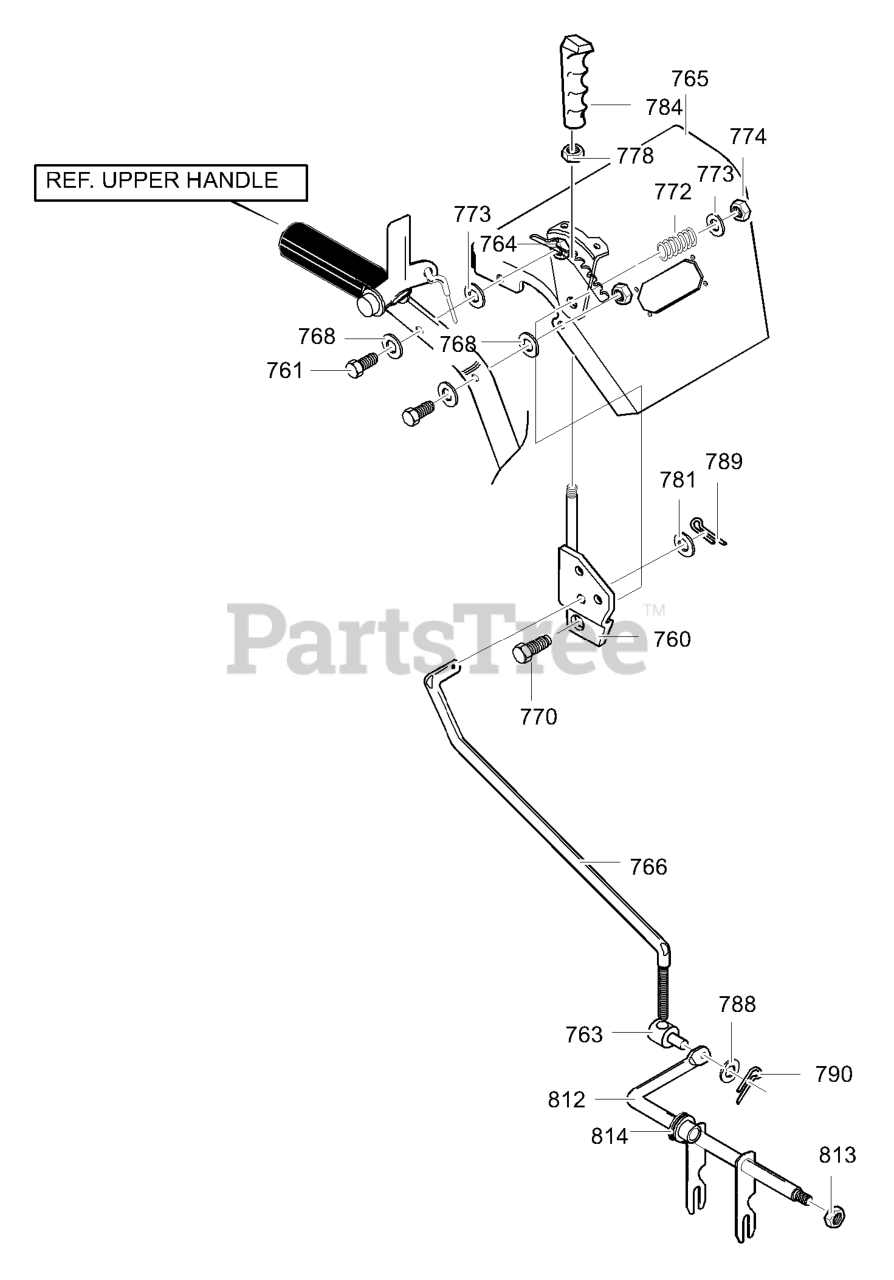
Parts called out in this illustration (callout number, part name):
760	HANDLE ASSY SPD CTRL
761	SCREW, 5/16-18 x 1.75
763	NUT, TRUNNION
764	NUT, 5/16-18 HEXWDFLLK
765	ASSY. BAY LT
766	ROD, SPEED CONTROL
770	SCREW 3/8-16X2.00
773	FLATWASHER
774	NUT, 3/8-16 HEXNYL
778	NUT, 3/8-16 REGHEX
781	FLATWASHER
784	HANDLE 3/8-16
788	FLATWASHER
789	PIN, COTTER
790	COTTER PIN
812	ROD, ASSY YOKE
813	RING, RETAINER
814	BEARING, FLANGE
